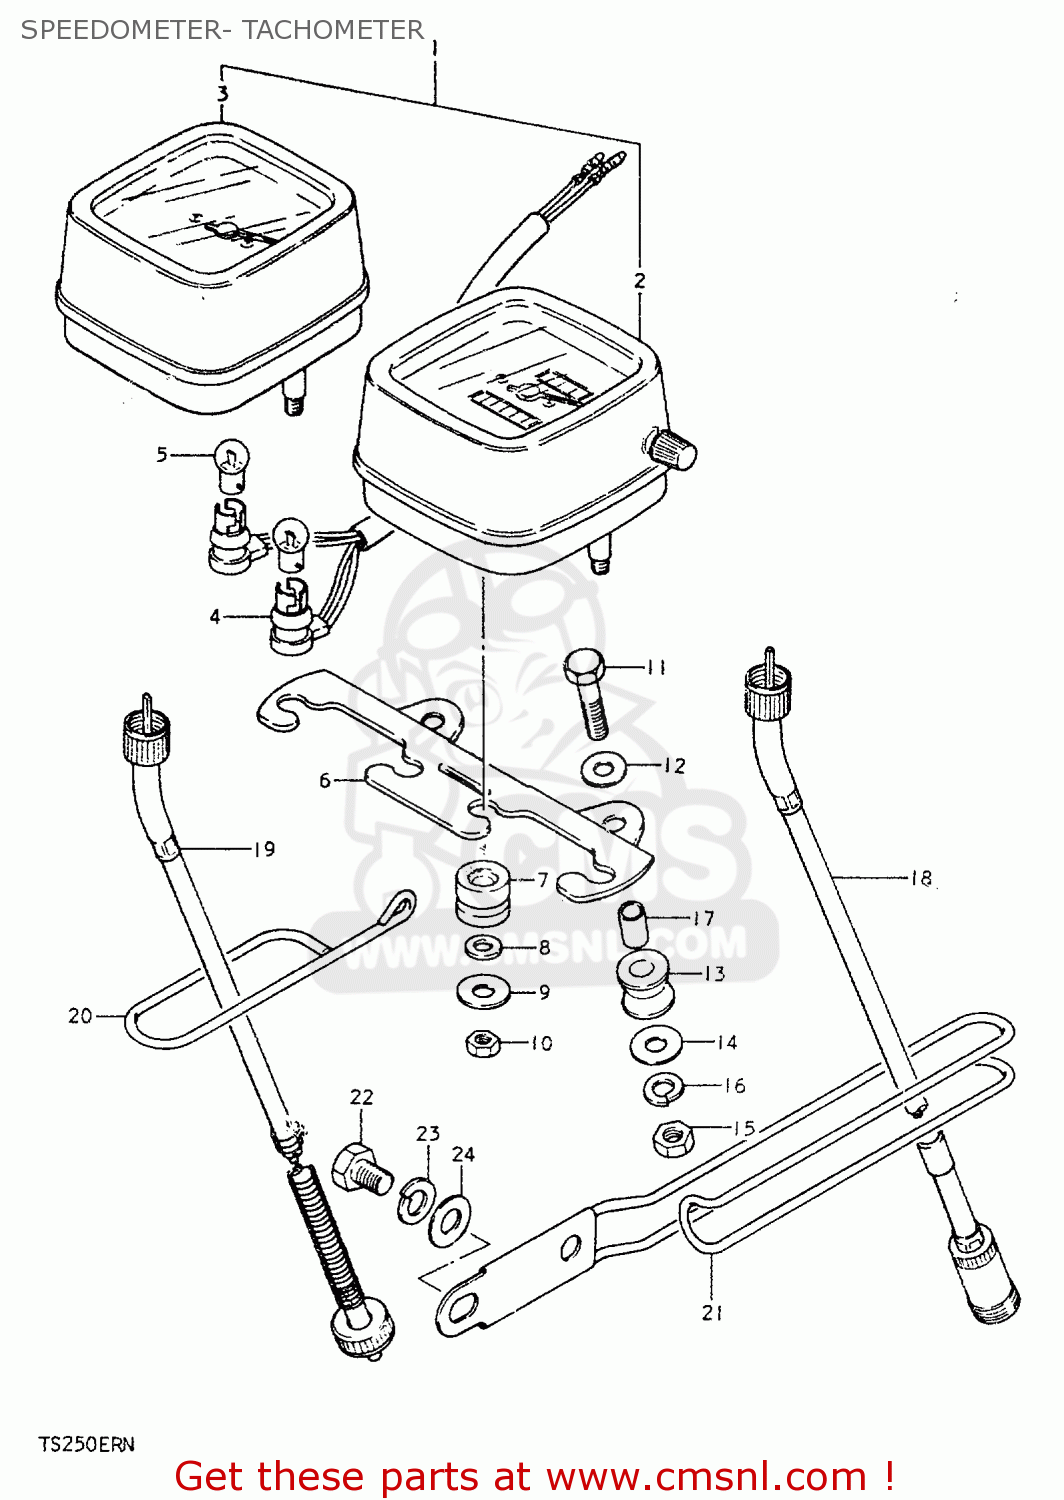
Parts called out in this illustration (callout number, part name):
1	SPEEDOMETER & TACHOMETER (KILO SCALE)
2	SPEEDOMETER (KILO SCALE)
3	TACHOMETER
4	SOCKET,METER
5	BULB(6V/3W)
6	BRACKET,METER
7	CUSHION,METER
8	LOCK WASHER
9	WASHER,METER
10	NUT
11	BOLT
12	WASHER
13	CUSHION
14	WASHER
15	NUT
16	LOCK WASHER
17	SPACER (6.1X8X15.5)
18	CABLE ASSEMBLY,SPEEDOMETER
19	CABLE ASSEMBLY,TACHOMETER
20	GUIDE,TACHOMETER CABLE
21	GUIDE,CABLE
22	BOLT 8X12
23	LOCK WASHER
24	WASHER
